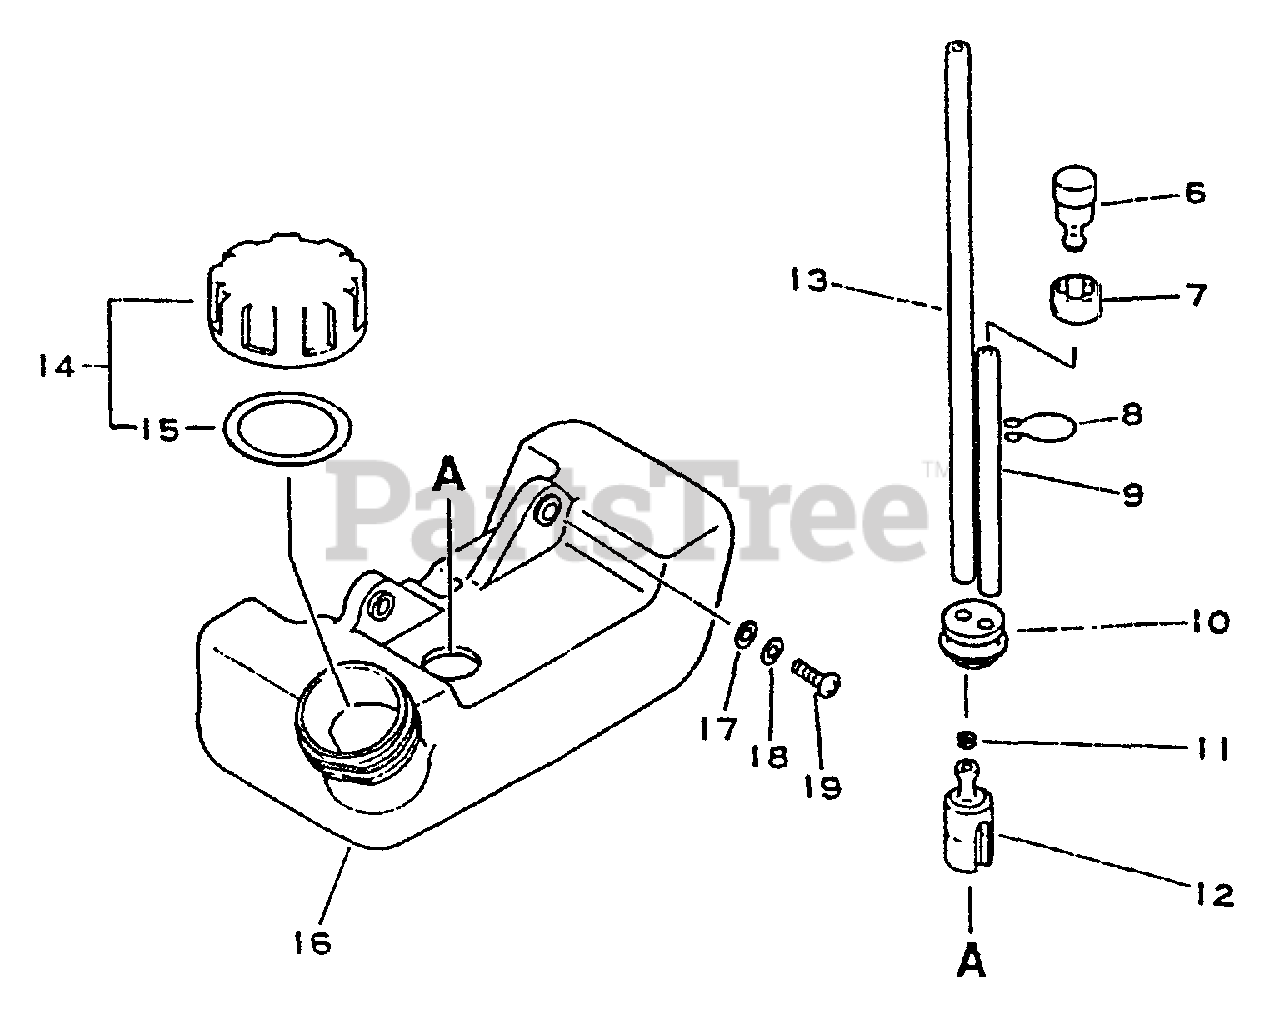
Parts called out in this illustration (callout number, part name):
6	VENT ASSY
7	HOLDER, VENT
8	CLIP, TUBE
9	PIPE, FUEL RETURN 3×6×70
10	GROMMET, FUEL
11	CLIP 6 MM
12	FILTER, FUEL
13	PIPE, FUEL 3x-5x-180
14	CAP ASSY
15	GASKET, FUEL CAP
16	TANK, FUEL
17	WASHER 5.5×12×0.8
18	WASHER, SPRING 5
19	SCREW 5×16
